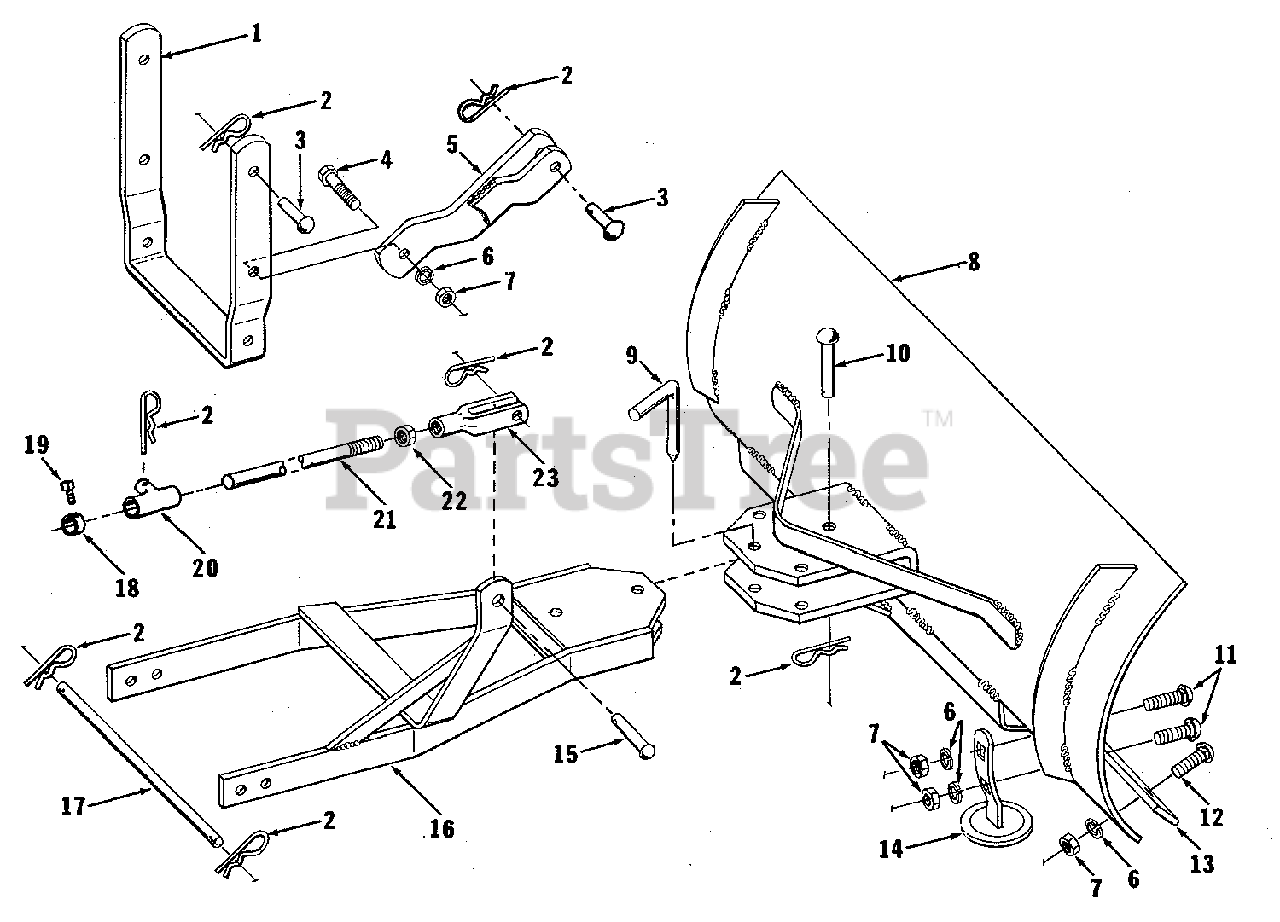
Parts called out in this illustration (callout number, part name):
2	CLIP, Spring
4	SCREW, Hex Head, Cap, 3/8-16 x 1-1/4
5	ARM, Support
6	WASHER, Lock, 3/8
7	NUT, Hex, 3/8-16
11	BOLT, Carriage, 3/8-16 x 1
12	BOLT, Carriage, 3/8-16 x 3/4
19	SCREW, Set, 5/16-18 x 3/8
22	NUT, Hex, 1/2-20
23	YOKE, End Adjustment.
